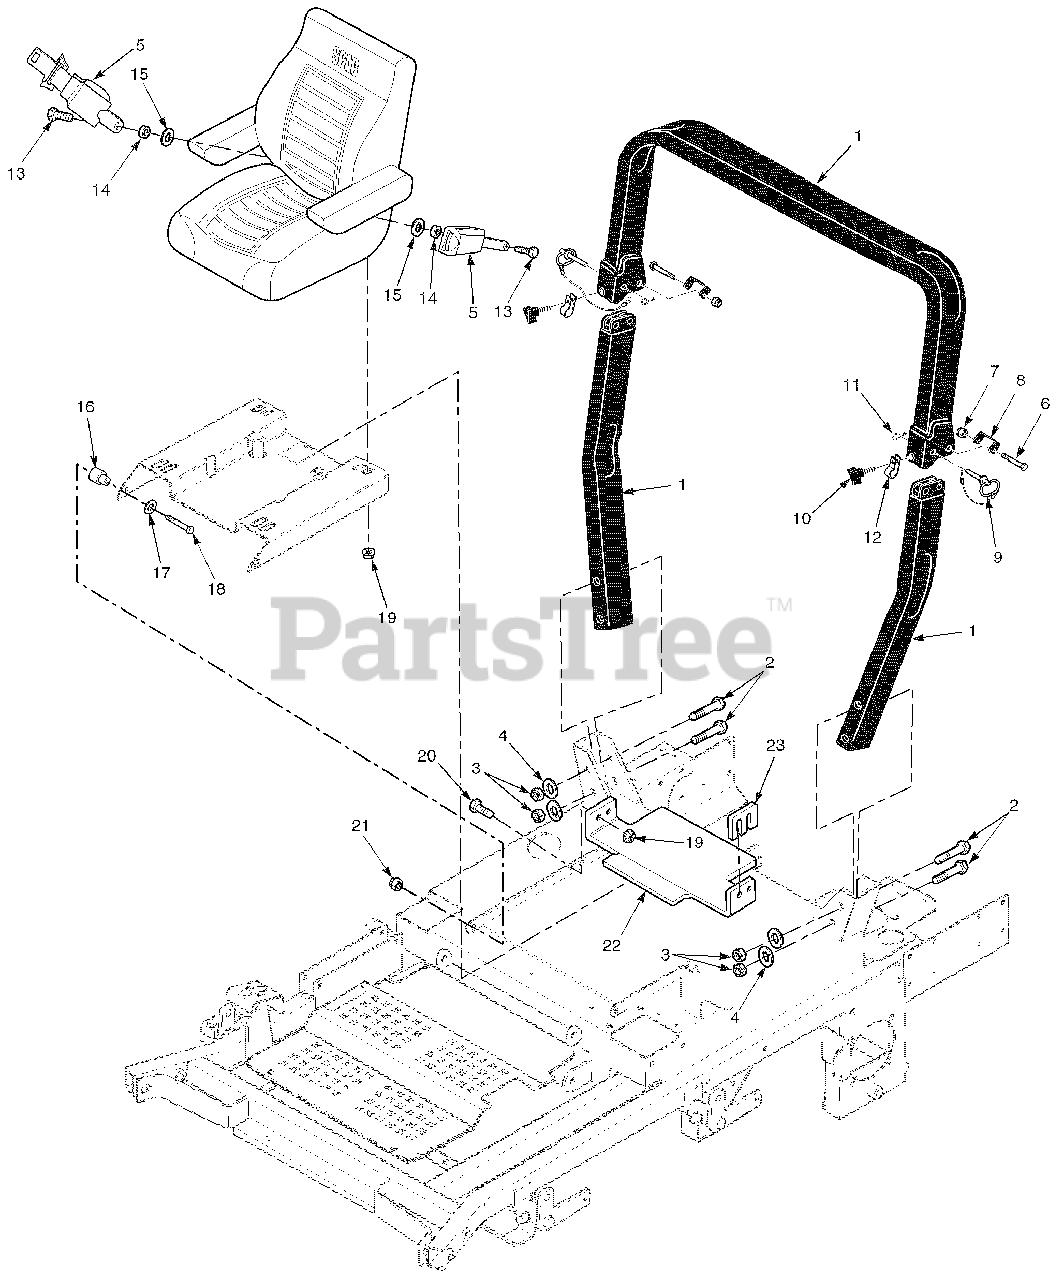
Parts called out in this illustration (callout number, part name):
1	STT, ROPS Acessory
2	Bolt, Hex Head 1/2-13 x 4-1/2"
3	Nut, Center Lock 1/2-13
4	Flatwasher, 1/2-.562 x 1.375 x .109
5	Retractable Seat Belt
6	Bolt, Hex Head 1/2-13 x 3-1/2"
7	Nut, Center Lock 1/2-13
8	Bracket, Stop
9	Pin
10	Thumb Screw, 5/16-18 NC x 3/4"
11	Hair Pin, Cotter
12	Clamp
13	Bolt, Hex Head 7/16-20 x 1"
14	Spacer
15	Flatwasher, 7/16-.500 x 1.25 x .083
16	Sleeve, Seat Base Mounting
17	Flatwasher, 3/8-.391 x .938 x .105
18	Bolt, Hex Head 3/8-16 x 2"
19	Nut, Serrated Flange 5/16-18
20	Bolt, Hex Head 5/16-18 x 1"
21	Nut, Elastic Stop 3/8-16
22	Bracket, Seat Hold Down w/Decal
23	Spacer, Seat Hold Down
